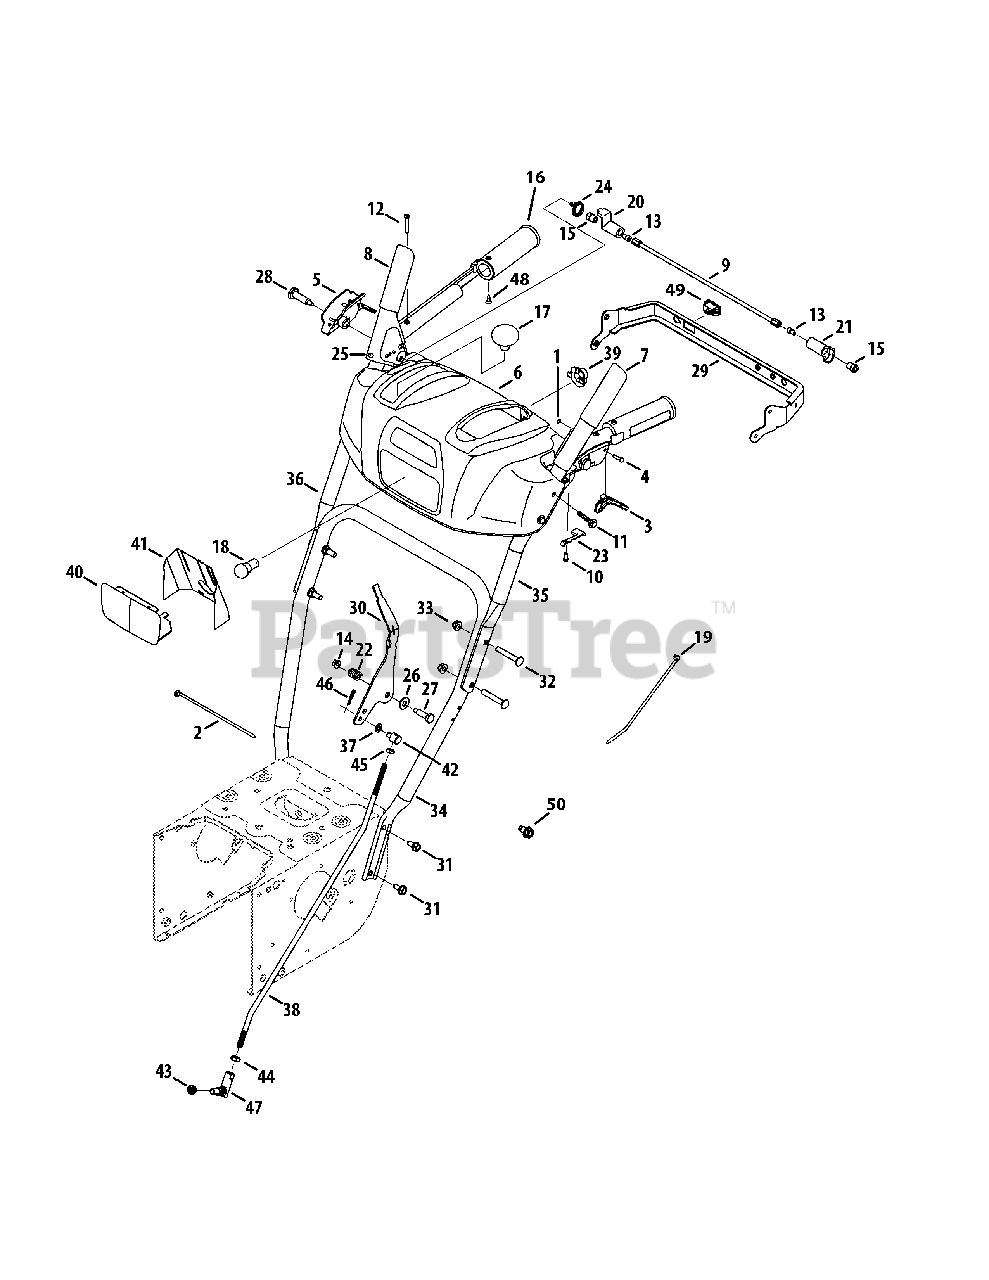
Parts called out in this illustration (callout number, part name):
2	Cable Tie
3	Clutch Trigger
5	Handle Clutch Lock LH Assy
5	Handle Clutch Lock RH Assy
6	Handle Panel, includes Ref. 40 & 41
7	Handle Engagement Assembly LH
8	Handle Engagement Assembly RH
10	Screw, 8-16 x 0.50
11	Screw, 1/4-20 x 1.625
12	Screw, 10-24 x 1.375
13	Socket Screw, 1/4-20 x .50
14	Flange Lock Nut, 1/4-20
15	Shoulder Nut, 1/4-20
16	Heated Grip
17	Shift Knob
19	Cable Tie
21	Clutch Lock Cam
22	Compression Spring
23	Clutch Lock Spring
24	Torsion Spring
25	Rubber Bumper
26	Flat Washer, .385 x .87 x .06
27	Shoulder Screw, .374 x 1.05
28	Shoulder Screw, 1/4-20 x 1.345
29	Panel Bracket
31	Hex Screw, 5/16-18 x .750
32	Carriage Screw, 5/16-18 x 2.00
33	Nut, Flangelock, 5/16-18
34	Lower Handle
35	Upper Handle LH
36	Upper Handle RH
37	Flat Washer, .320 x .600 x .060
38	Shift Rod, .343 OD
39	Light Socket
41	Lens Label
42	Ferrule, 5/16-18 x .312 Dia
43	Jam Lock Nut, 3/8-24
44	Jam Nut, 3/8-24
45	Nut, Jam 5/16-18
46	Bow-Tie Cotter Pin
47	Ball Joint
48	AB Screw, #10-16 x .625
49	Heated Grip Switch
50	Screw, TT, 1/4-20 x .500 (For ground wire)
